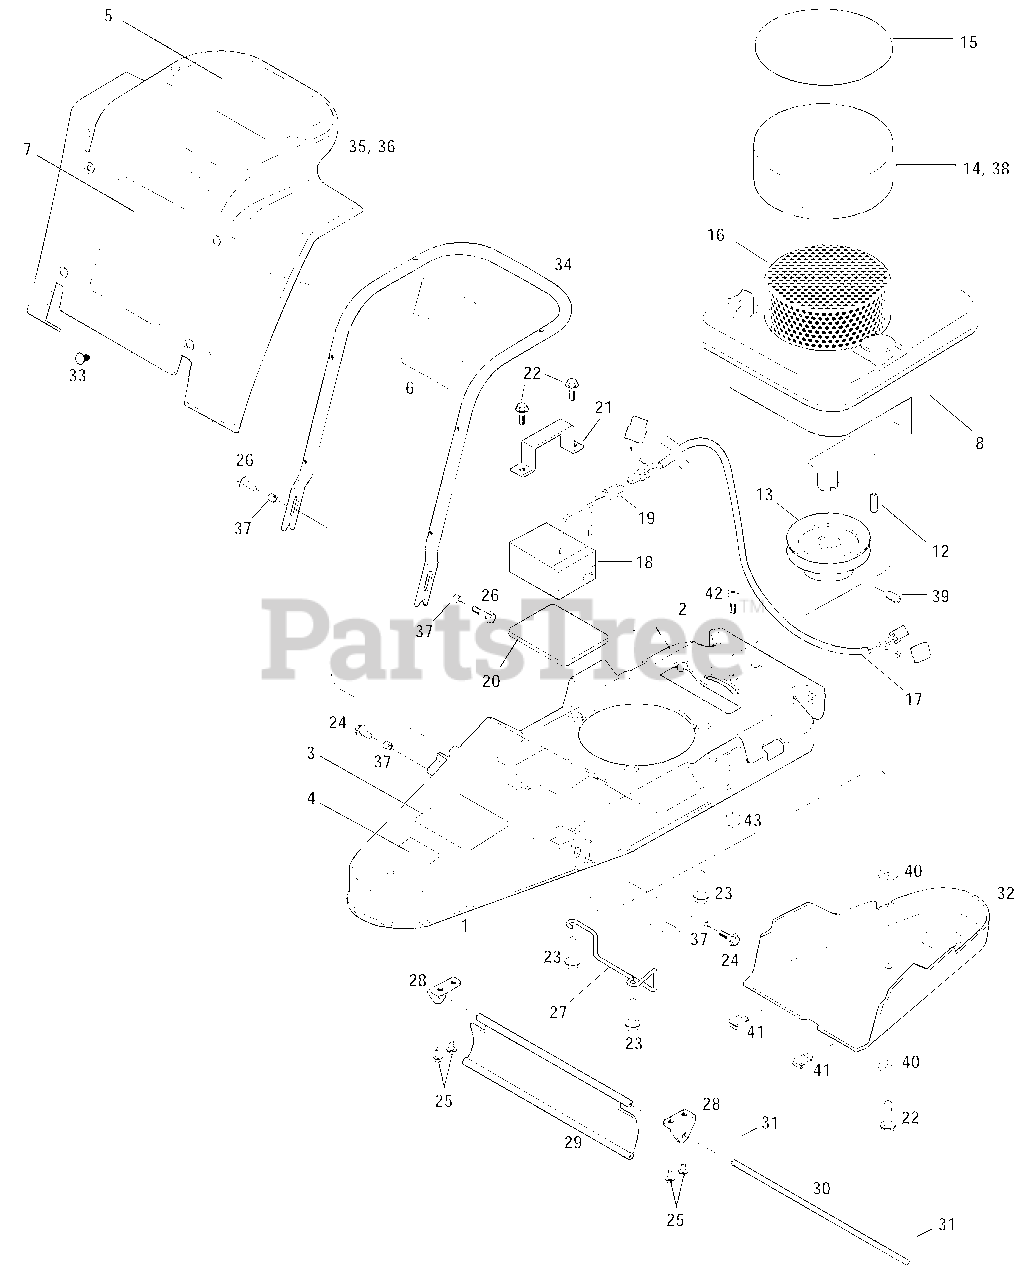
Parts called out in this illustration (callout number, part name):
1	Deck with decals.
2	Decal-Hot Surface
3	Decal-Warning/Thrown Objects
4	Decal-Danger Feet/Hands
5	Decal-Engine Cover
6	Decal-Parallel Trim Control
7	Decal-Logo, 6HP.
8	Engine-Quantum, 4HP Std.
12	Key, 3/16" x 1" Sq.
13	Pulley, 4" OD
14	Engine Debris Guard/Foam
15	O-Ring/Engine Debris Guard
16	Engine Debris Guard
17	Wire Harness.
18	Battery.
19	Battery Connector.
20	Battery Pad.
21	Battery Bracket.
22	Hex Hd. Flange Screw, 5/16-18 x 1
23	Hex Hd. Flange Screw, 3/8-16 x 1-1/2
24	Hex Hd Flange Screw, 1/4-20 x 3/4
25	Hex Hd Flange Screw, 1/4-20 x 5/8
26	Hex Hd Flange Screw, 1/4-20 x 1
27	Belt Guide
28	Flap Bracket
29	Deflector Shield
30	Deflector Shield Rod
31	E-Ring, 5/16"
32	Belt Cover
33	Push-In Fastener
34	Engine Cover Support
35	Engine Cover w/decals.
36	Engine Cover w/decals.
37	Spacer
39	Set Screw
40	Washer
41	Clip
42	Socket Hd. Capscrew, 1/4-20 x 1
43	Toplock Nut, 1/4-20
